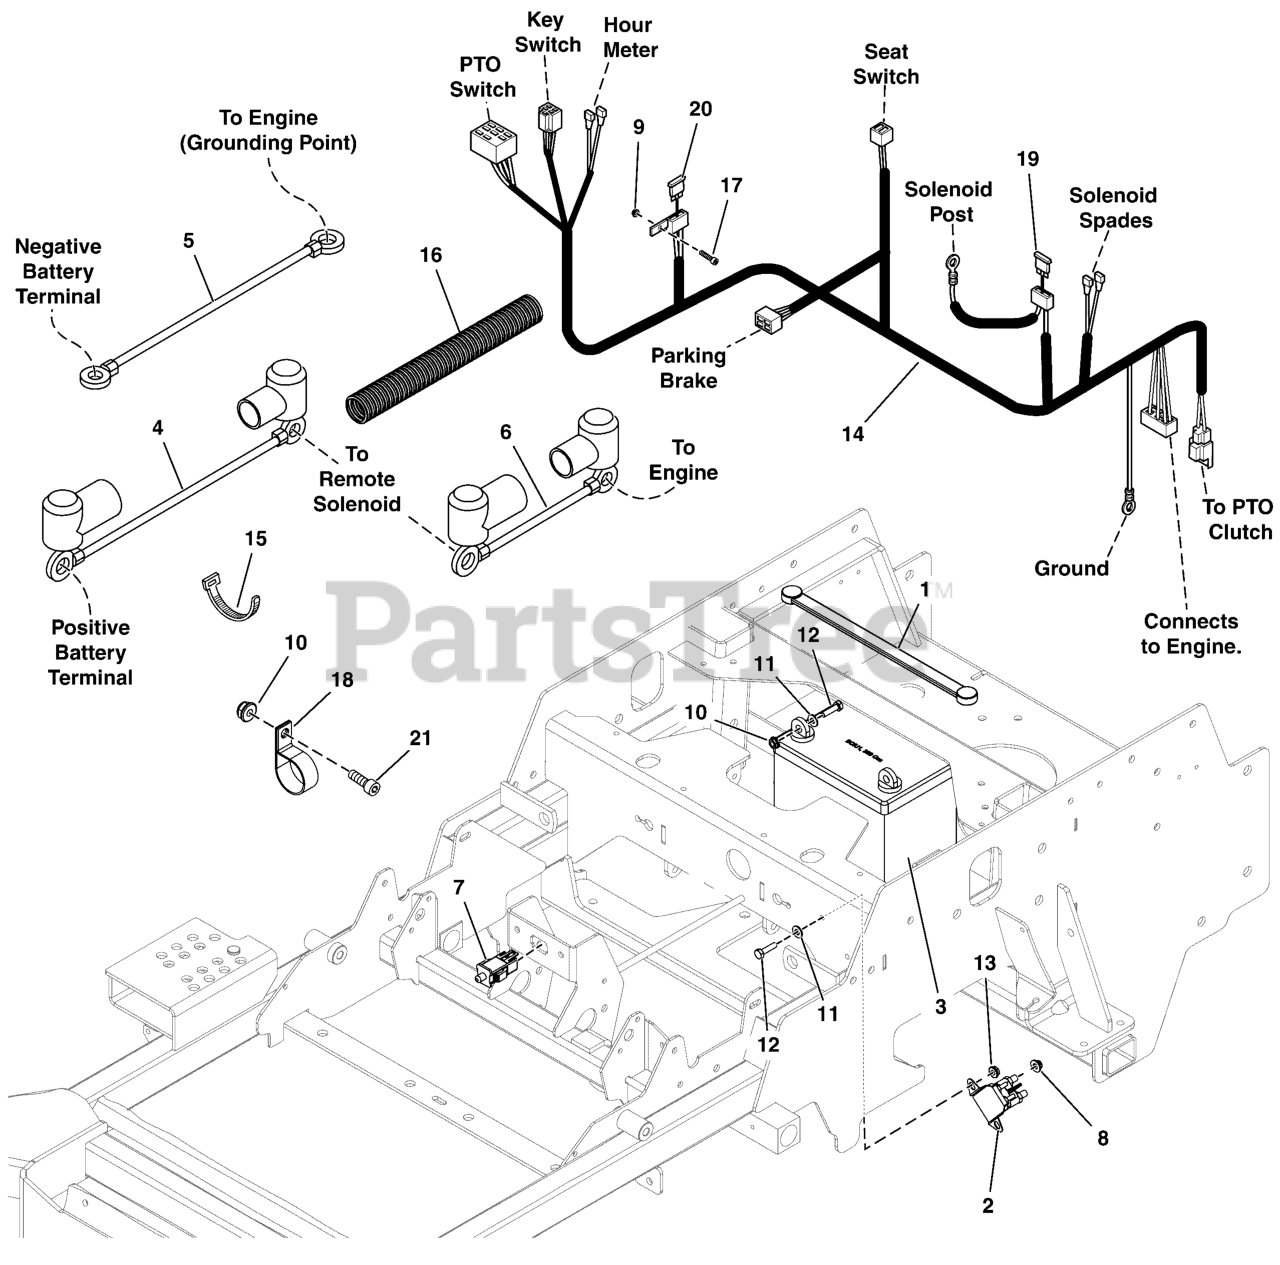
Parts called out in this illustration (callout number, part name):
1	STRAP, Rubber, 13"
2	SOLENOID, 1/4-20 STD, 2 Spade
3	BATTERY, WET ( BCIU1, 340 CCA)
4	BATTERY CABLE, POS, 22, 1/4-5/16
5	BATTERY CABLE, NEG, 14, 5/16-13/32
6	BATTERY CABLE, POS, 22, 1/4-5/16
7	SWITCH, DP, NO/NC, Snap-In
8	NUT, 1/4-20, Keps, Conical Washer
9	NUT, Nylock, #10-24
10	NUT, Serrated, Flange, 1/4-20, GR5
11	WASHER, Flat, 1/4
12	CAPSCREW, Hex Head, 1/4-20 x 3/4 (stiffener to top of cover)
13	NUT, Flange Nylock , 1/4-20
14	HARNESS, SMALL, ZTR WIRING
15	TIE, SELF-LOCKING, 12"
16	WIRE LOOM, 3/8 ID X 18 IN
17	SCREW, #10-24 X 3/4", ROUND PHILLIPS
18	CLAMP, VINYL INSULATED, 1.00
19	FUSE, ATO, 20 AMP (SV)
20	FUSE, ATO, 15 AMP (SV)
21	CAPSCREW, Button Allen Head, 1/4-20 x 3/4
